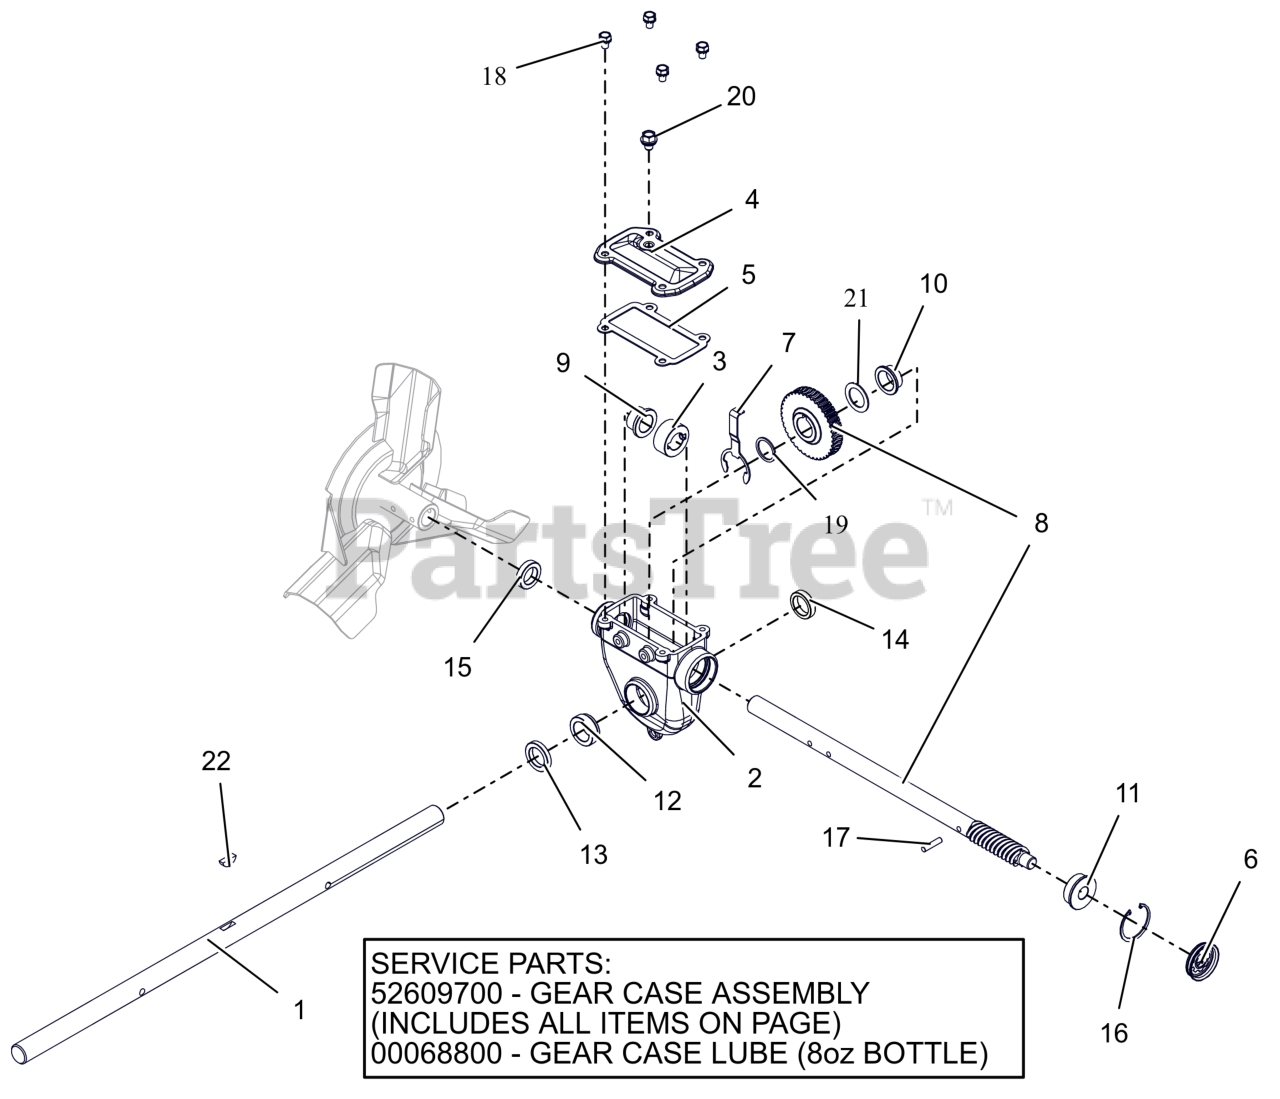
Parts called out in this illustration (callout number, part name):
1	SHAFT, RAKE-28"
2	GEARCASE, LARGE MACHINED
2	GEAR CASE, 28" IRON PRO TOP-LD
2	ARIENS L3 LUBE, 8 OZ BOTTLE
3	THRUST COLLAR, .875"ID SLIPFIT
4	COVER, TOP - LARGE IRON
5	GASKET, TOP - LARGE GEARCASE
6	COVER, GEAR CASE 1.75"
7	BUSHING RETAINER, LARGE
8	ASSY, WORM SHAFT & GEAR
9	BSHG-FLG .879X1.128X.75X1.45
10	BSHG-FLG 1.006X1.128X.555X1.45
11	BSHG-FLG .628X1.503X.58X1.725
12	BSHG-FLG LARGE, RIGHT
13	SEAL-OIL .999X1.500X.250 TBC29
14	SEAL-OIL .999X1.375X.312 TBC29
15	SEAL-OIL .873X1.375X.312 TBC29
16	RG-RTNG-INT 1.750X.062
17	PIN-STR .250X1.12 6150
18	BLT, SEMS .31-18X.50 G5 ZCC
19	WSHR, FLT 1.010X1.250X.068 ZCC
20	SCR, .380-15X.500 W/SEAL WASHER
21	WSHR, FLT 1.010X1.505X.062 ZCC
22	KEY-WDRF .25X.875 HRD #A
